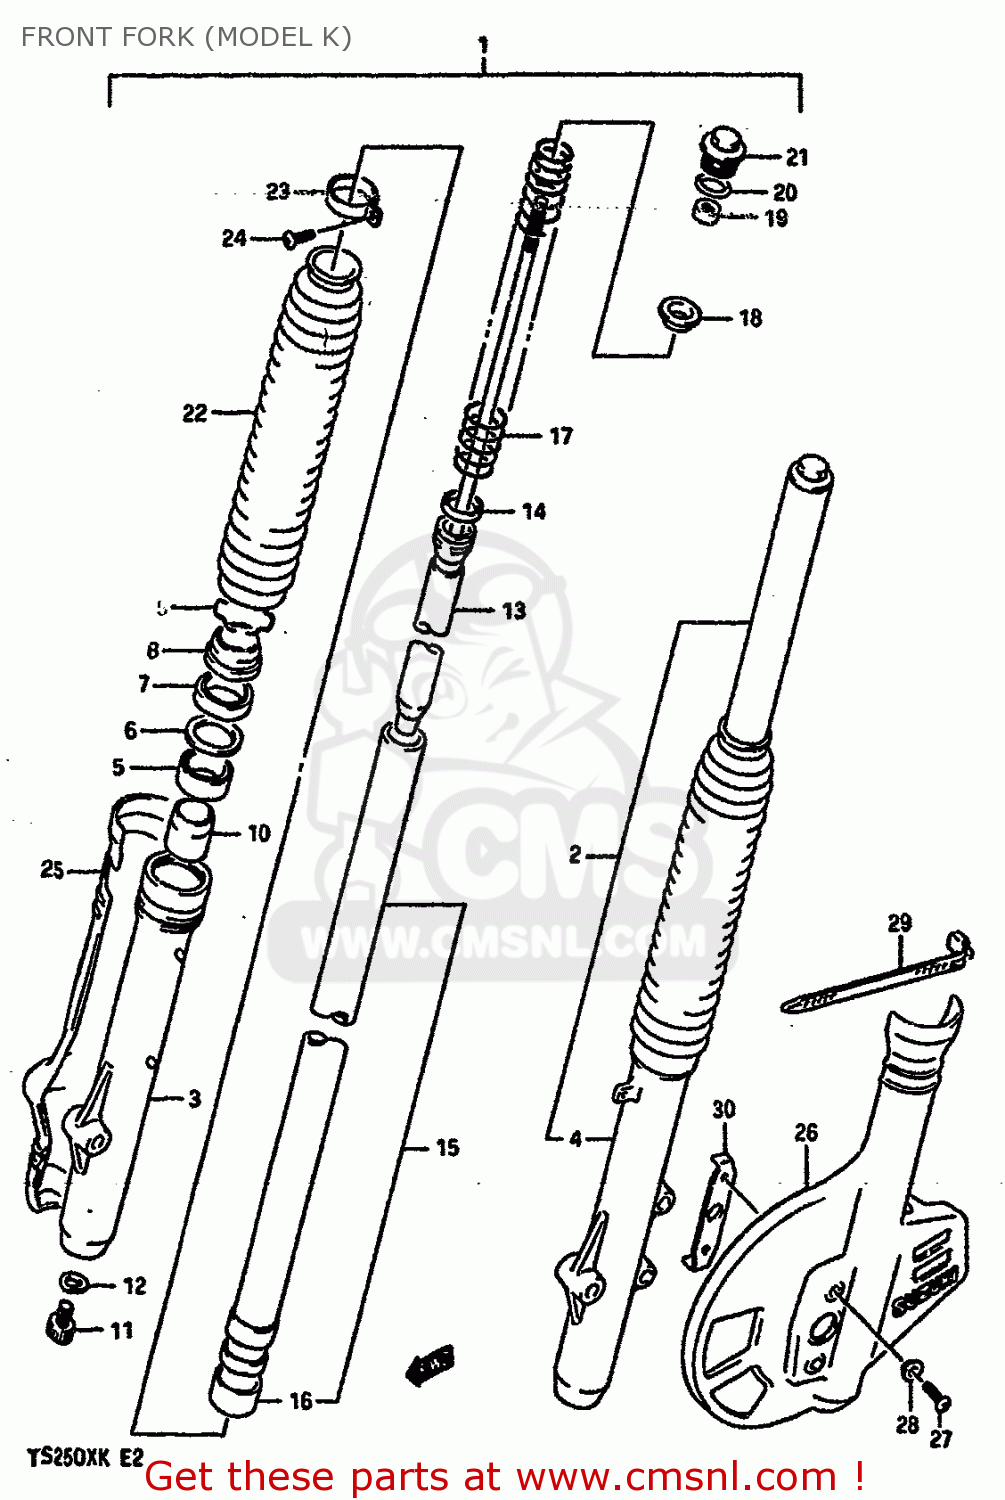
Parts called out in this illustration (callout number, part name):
1	DAMPER ASSY,RH
2	DAMPER ASSY,LH
3	TUBE,OUTER RH
4	TUBE,OUTER LH
5	METAL,SLIDE
6	WASHER(40X50X2.3)
7	SEAL,OIL
8	SEAL,DUST
9	RING,STOPPER
10	PIECE,OIL LOCK
11	BOLT,CYLINDER
12	GASKET,CYLINDER (NAS)
13	CYLINDER
14	RING,PISTON
15	TUBE,INNER
16	PISTON
17	SPRING
18	GUIDE
19	NUT,ROD
20	O RING
21	CAP
22	BOOT (BLUE)
23	BAND,BOOT
24	SCREW
25	PROTECTOR,FORK RH (BLACK)
26	PROTECTOR,FORK LH (BLACK)
27	SCREW 6X12
28	WASHER
29	CLAMP
30	PLATE,PROTECTOR LH
